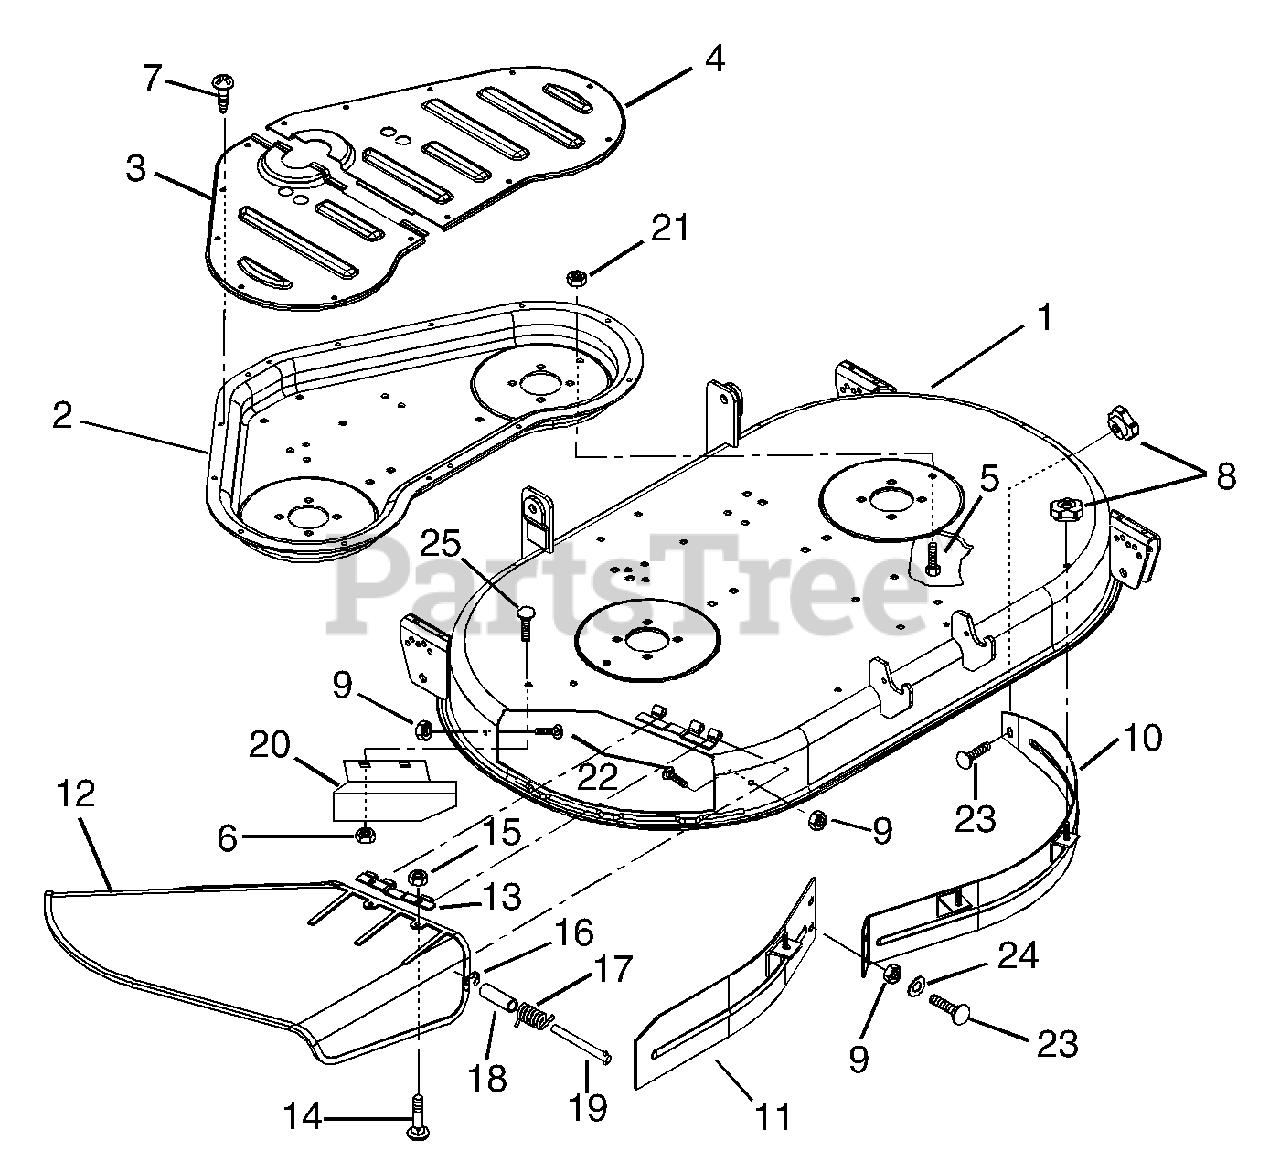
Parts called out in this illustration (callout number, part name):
1	MWR, 42" SIERRA W/DECALS
2	REINFORCEMENT, DECK
3	COVER, PLATE 3 RIBS
4	COVER, PLATE 5 RIBS
5	@BLT-HEX .38-16X1.00 GR5 YWZC
6	@NUT-LK-CTR .38-16 YWZC
7	@SCR-TAP .31-18X.50 HWH TR YWZ
8	KNOB
9	@NUT-LK-CTR .31-18 YWZC
10	WELDMENT, BAFFLE UPPER LH
11	WELDMENT, BAFFLE UPPER RH
12	DEFLECTOR, CHUTE
13	HINGE PLATE
14	@BLT-RDHDSQNK .25-20X.75 G5YZ
15	@NUT-SPNLK-FLG .25-20 YWZC
16	RG-RTNG-EXT .312X.025
17	SG-TORS .095X.50X 1.0
18	BSHG-SLV .334 X .502 X 1.437
20	DEFLECTOR (BAFFLE)
21	@NUT-LK-NYL .38-16 YWZC
22	@BLT-HEX .31-18X.75 GR5 YWZC
23	@BLT-RDHDSQNK .31-18X.75 G5YZ
24	@WSHR-FL-STL.38X.875X.083 YWZC
25	@BLT-HEX .38-16X.75 GR5 YWZC
